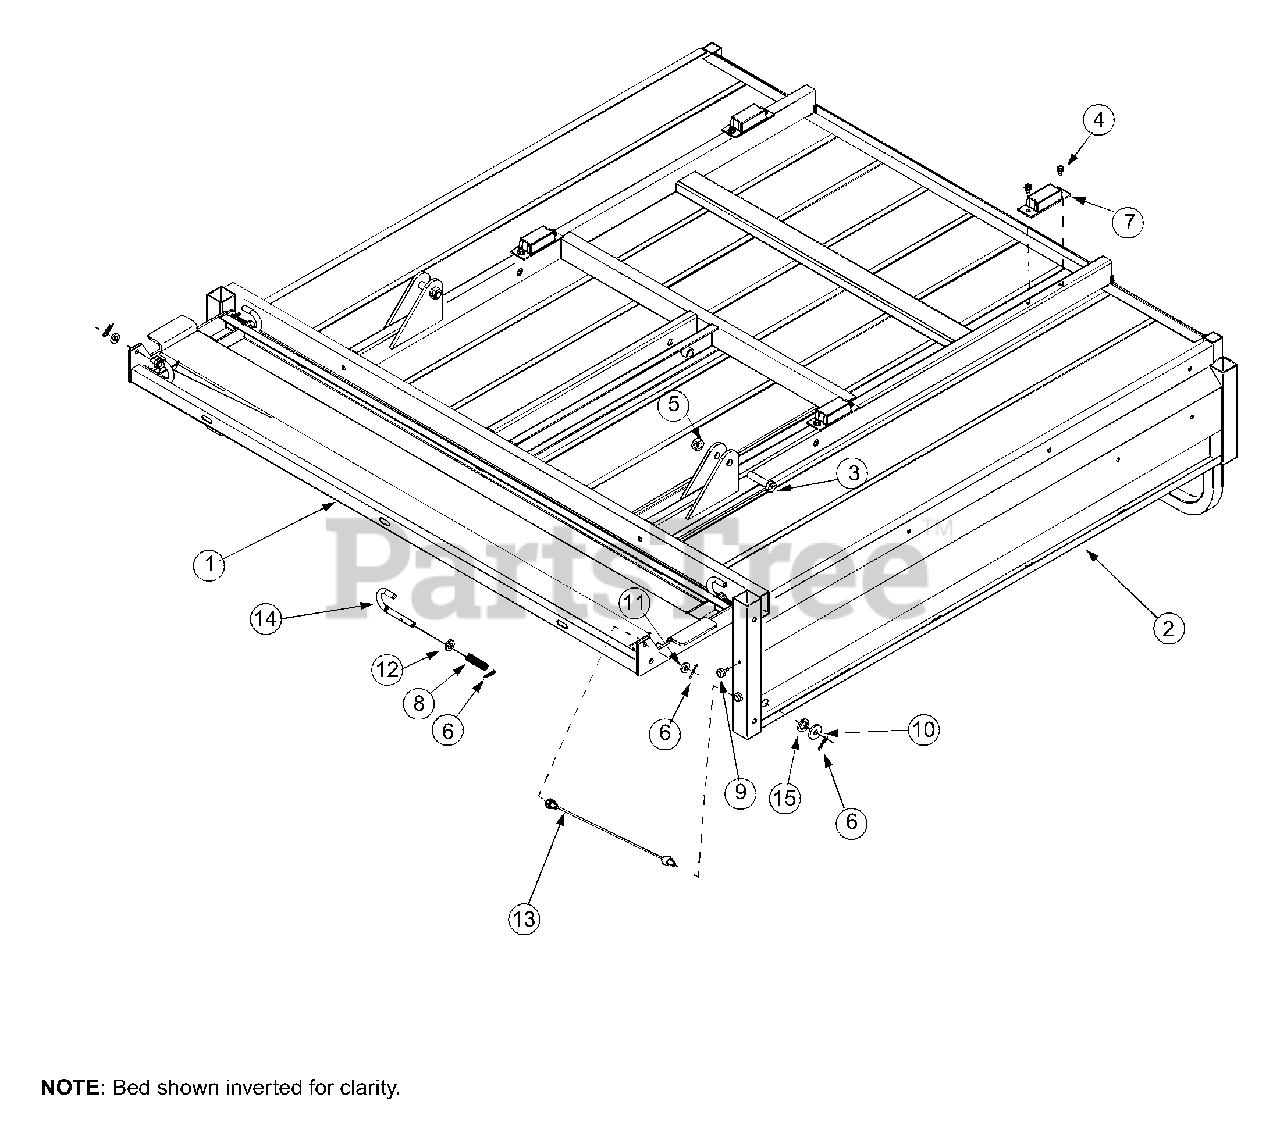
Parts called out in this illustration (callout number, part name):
1	Tailgate Assembly
2	Bed Assembly, Utility
3	Screw, Hex, 1/5-13 x 2.0, Gr5
4	Screw, Self-tapping, 1/4-20 x 0.500
5	Nut, Hex Lock, 1/2-13
6	Cotter Pin, .072Dia x 1.13LG
7	Bumper, Extension Suspension
8	Compression Spring, .406 x .531 x 1.75 LG
9	Bumper, .62Dia x .3
10	Washer, Flat, .64 ID x 1.0 x .12
11	Washer, Flat, .344 x .750 x .120
12	Washer, Flat, .407 x .812 x .135 HDN
13	Cable, LIft 16.16 LG
14	Handle, Deck Release
15	Spacer, Shoulder .625 Dia x .324 Dia
